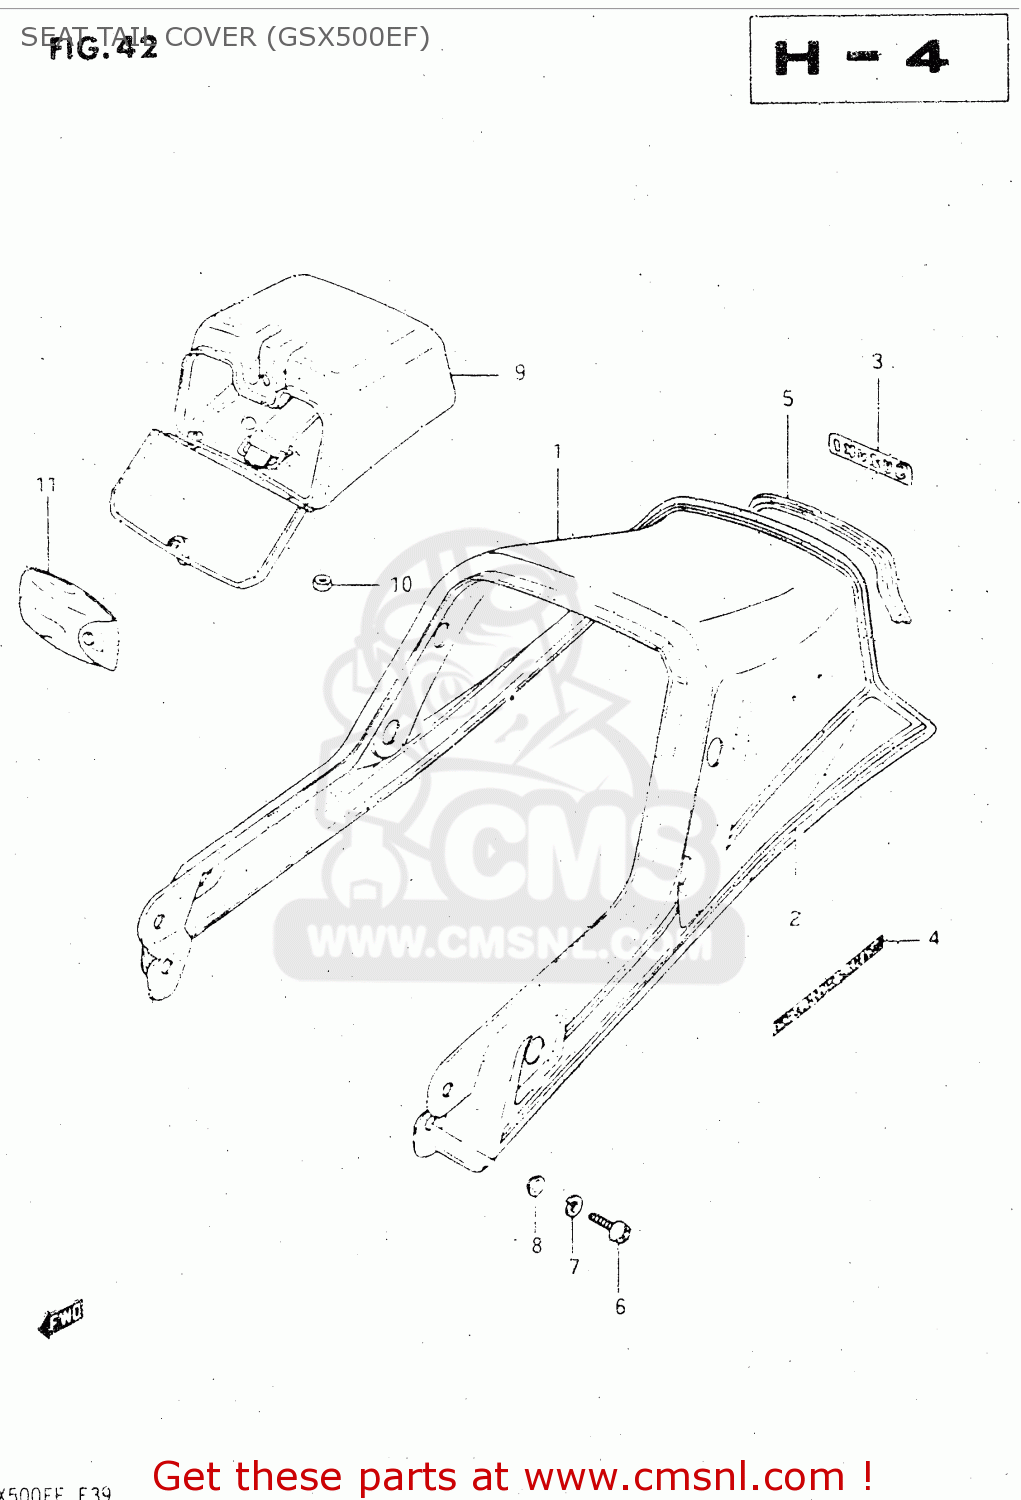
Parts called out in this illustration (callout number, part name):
1	COVER, SEAT TAIL
2	TAPE SET,SEAT TAIL COVER
3	EMBLEM(WHITE)
4	EMBLEM, FULL FROATER
5	BLIND,SEAT TAIL COVER
6	SCREW
7	LOCK WASHER
8	WASHER
9	BOX,SEAT TAIL
10	NUT
11	TOOL ASSY
